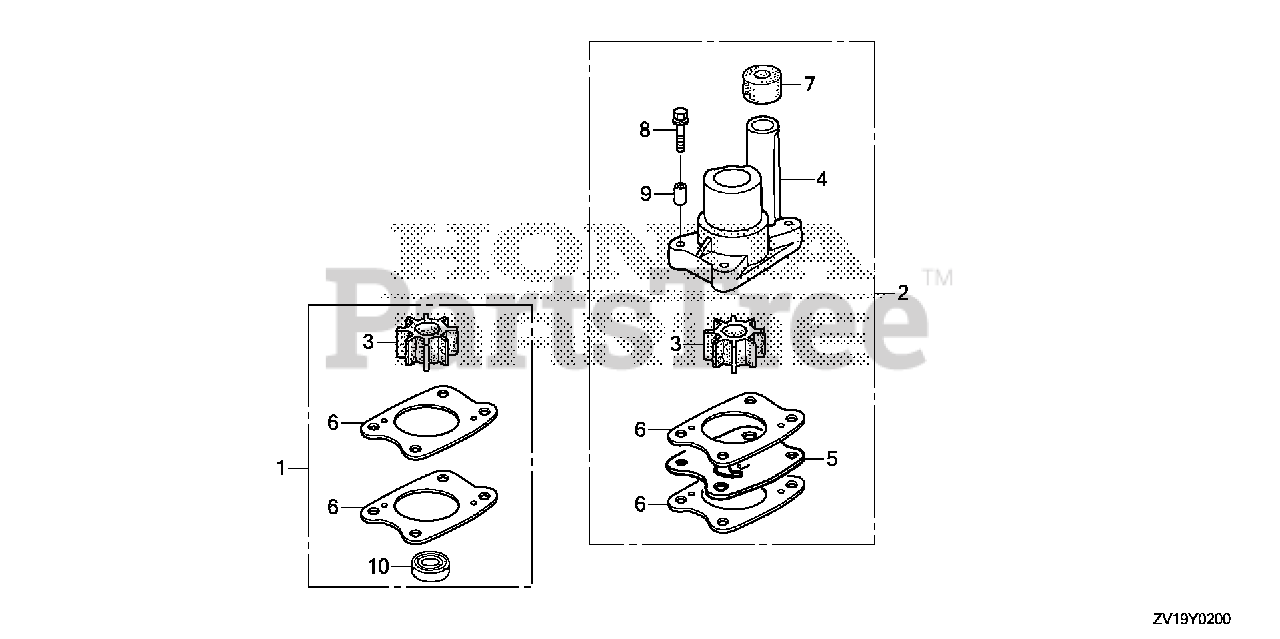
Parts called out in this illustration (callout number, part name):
1	IMPELLER KIT, WATER PUMP
2	PUMP KIT, IMPELLER
3	IMPELLER, PUMP
4	HOUSING, IMPELLER
5	COVER, IMPELLER
6	GASKET, IMPELLER
7	RING, WATER TUBE SEAL
8	BOLT-WASHER (6X29)
9	COLLAR B, DISTANCE
10	SEAL, WATER (13MM) (ARAI)
